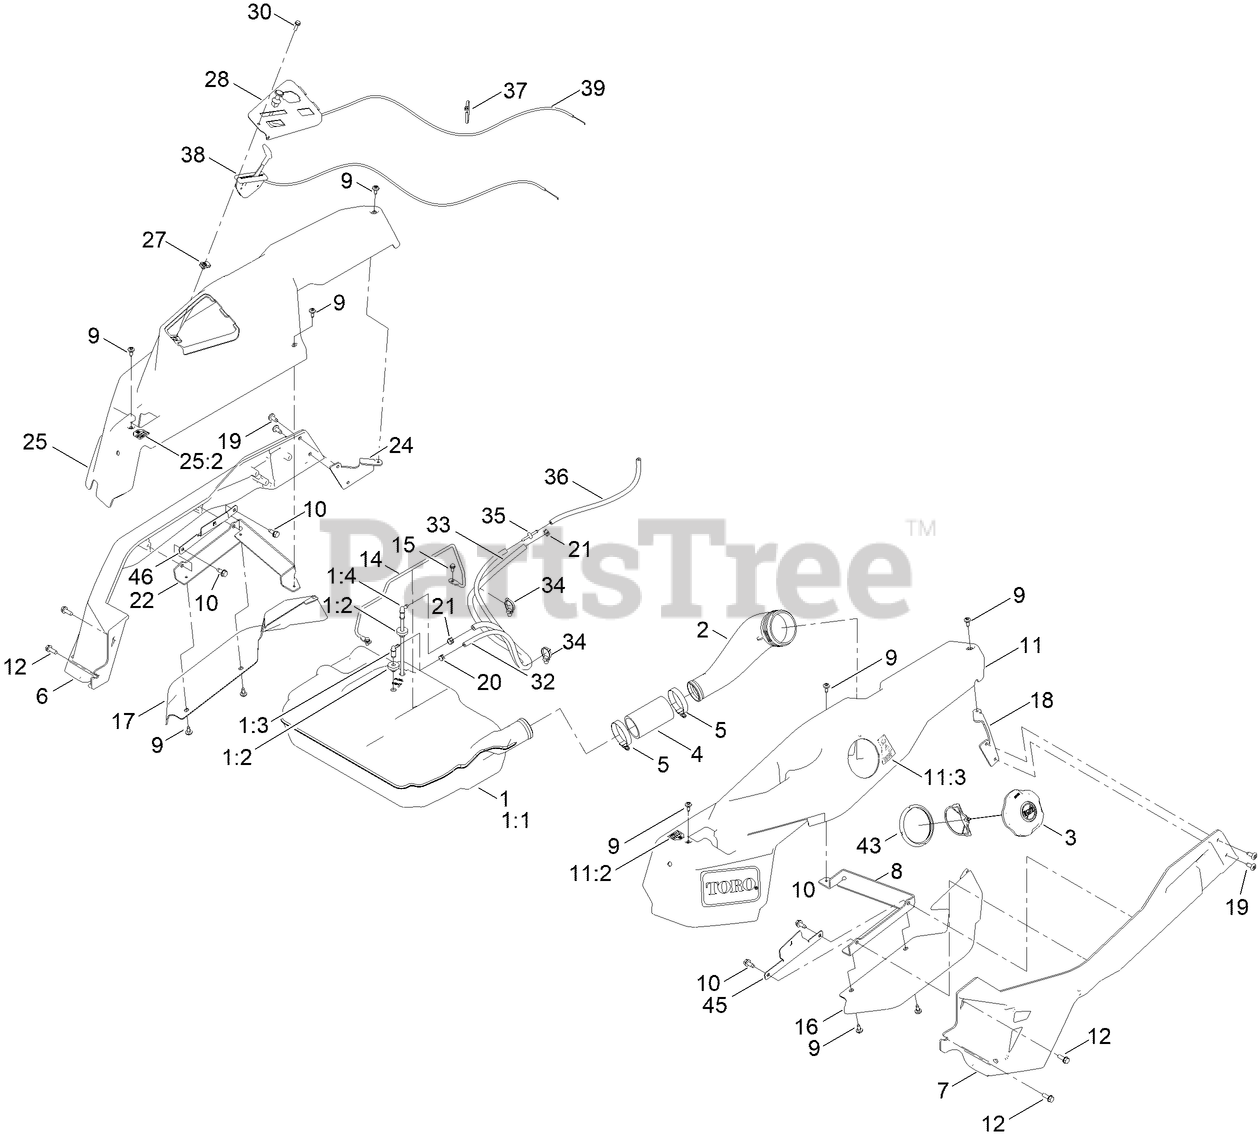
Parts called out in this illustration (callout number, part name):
1	FUEL TANK ASM
1:1	TANK-FUEL
1:2	BUSHING
1:3	FITTING-ELBOW 90
1:4	FITTING - PICKUP, FUEL
2	NECK-FILLER, FUEL
3	CAP-FUEL, RATCHETING
4	HOSE-FILLER, FUEL
5	CLAMP-HOSE
6	CAST-TUBE, RH [RED]
7	CAST-TUBE, LH [RED]
8	MOUNT-POD BRACKET LH
9	SCREW-SHOULDER
10	SCREW-HWHTF
11	POD ASM - LH W/DECALS
11:2	DECAL-CONTROL LEVER, LH
11:3	DECAL-FUEL FILL
12	SCREW-TAPTITE
14	ROD-HOLD DOWN
15	SCREW-HWH
16	FENDER-TIME CUTTER, LH
17	FENDER-TIME CUTTER, RH
18	BRACKET-REAR POD, LH
20	CLAMP-HOSE
21	CLAMP-HOSE
22	MOUNT-POD BRACKET RH
24	MOUNT-POD BRACKET RH
25	POD ASM - RH W/DECALS
25:2	DECAL-CONTROL LEVER, RH
28	PANEL-CONTROL
30	SCREW-HWH
32	HOSE-FUEL
33	HOSE-FUEL
34	CLIP-TIE
35	ADAPTER ORIFICE
36	HOSE-FUEL
37	TIE-CABLE
38	CABLE-THROTTLE
39	CABLE-CHOKE
43	RING-RETAINING
45	BRACKET-ALIGNMENT, POD LH
46	BRACKET- ALIGNMENT, POD RH
